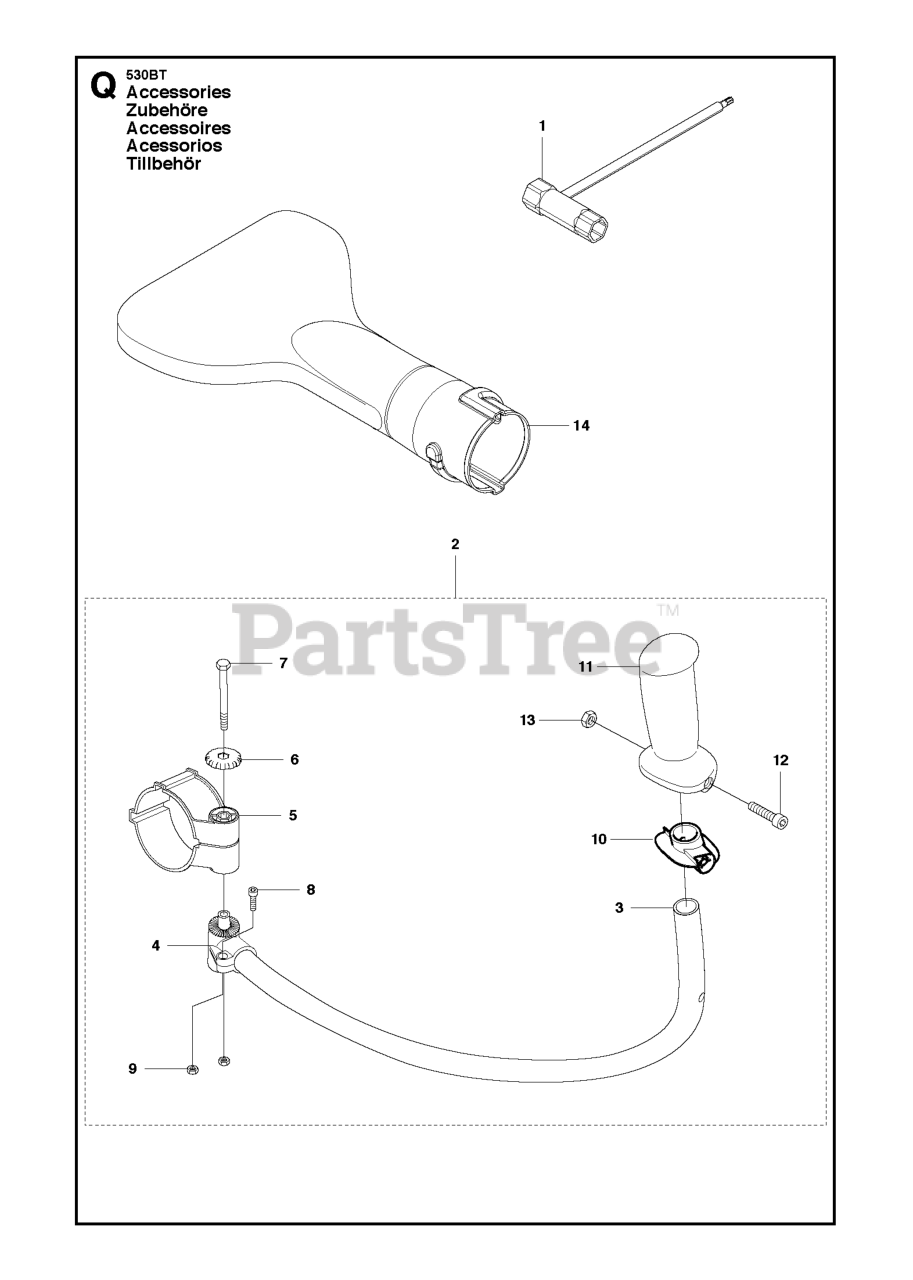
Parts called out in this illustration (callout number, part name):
2	HANDLEBAR ASSY
8	SCREW MC6S 5X10
14	FLAT NOZZLE
